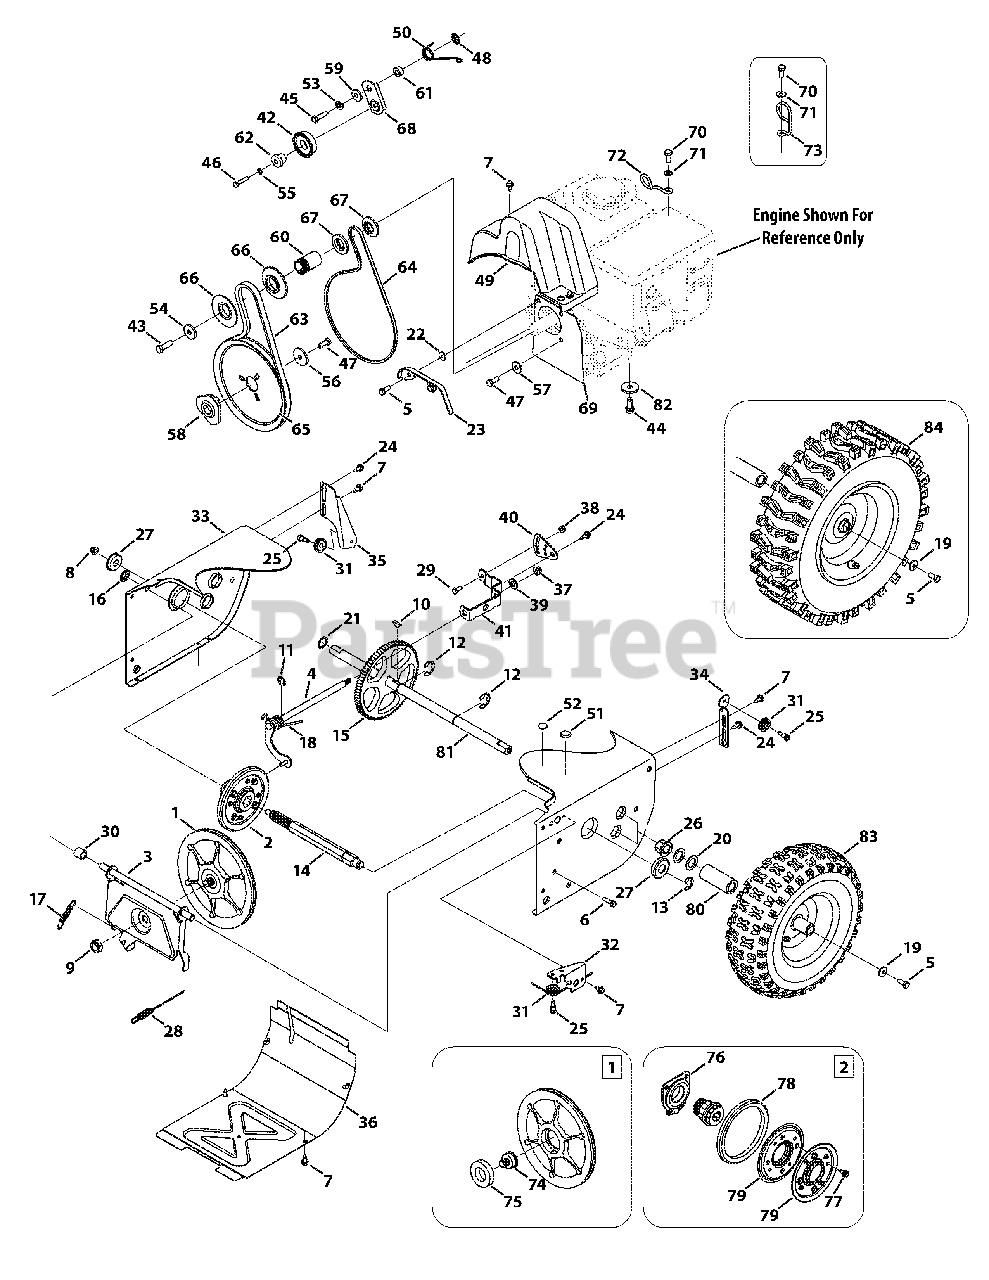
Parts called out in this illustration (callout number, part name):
1	Disc Assembly, Friction Wheel
2	Friction Wheel Assembly, 5.5 OD
3	Friction Wheel Support Bracket
4	Rod Shift Assembly
5	Hex Head Screw, 5/16-24 x .750
6	Taptite Screw, 1/4-20 x 1.000
7	Taptite Screw, 1/4-20 x .625
8	Flange Lock Nut, 3/8-16
9	Flange Nut, 5/8-18
10	Hi-pro Key, 3/16 x 3/4 Dia.
12	Retaining E-ring, .875 Dia.
13	E-ring, .750 Dia.
14	Hex Shaft, 7-Tooth
15	Gear, 80-Tooth
16	Speed Nut, .500
17	Extension Spring
18	Torsion Spring, .750 x .968
19	Bell Washer, .340 x .872 x .060
20	Flat Washer, .793 x 1.24 x .060
21	Flat Washer, .75 x 1.00 x .060
22	Washer, Flat, .385 x .62 x .063
23	Belt Cover
24	Shoulder Screw, .368 x .113, 1/4-20
25	Shoulder Screw, 1/4-28, .340 x .355
26	Hex Flange Bearing
27	Ball Bearing, 17 x 40 x 12
28	Wheel Clutch Cable, 44.95"
29	Hex Head Screw, 1/4-20 x .620
30	Spacer, .508 ID x .75 OD x .68
31	Cable Roller
32	Auger Cable Front Guide Bracket
33	Frame - Red
34	Auger Cable Guide Bracket
35	Drive Cable Guide Bracket
36	Frame Cover - Red
37	Flange Lock Nut, 5/16-18
38	Flange Lock Nut, 1/4-20
39	Washer, Flat, .469 x .875 x .105
40	Speed Selector Pivot Bracket
41	Speed Selector Shift Bracket
42	Idler Pulley Assembly
43	Hex Screw, 3/8-24 x 1.25
44	Sems Screw, 3/8-16 x 1.00
45	Hex Screw, 5/16-24 x 1.25
46	Hex Screw, 1/4-20 x 1.25
47	Hex Screw, 5/16-24 x .875
48	Push-on Nut, .25 Dia.
49	Belt Cover - 28" Models
49	Belt Cover - 26" Models
49	Belt Cover - 24" Models
50	Torsion Spring, .850 ID x .333
51	Plug, 3/8 ID
52	Plug, 1/2 ID
53	Lock Washer, 5/16
54	Flat Washer, .406 x 1.25 x .157
55	Washer, Lock, 1/4
56	Flat Washer, .34 x 1.50 x .150
57	Shoulder Space
58	Adapter Pulley, .75 Dia.
59	Shoulder Spacer, .3175 x .5 x .0975
60	Spacer, .875 ID x 1.185 OD
61	Spacer, .340 x .750 x .330
62	Shoulder Space, .260 x .785 x .538
63	Auger Drive Belt - 28" Models
63	Auger Drive Belt - 24" & 26" Models
64	Wheel Drive Belt - 28" Models
64	Wheel Drive Belt - 24" & 26" Models
65	Auger Drive Pulley, 8.1 x .5
66	Pulley Half, 2.600 OD
67	Pulley Half, 3/8 x 1.716 OD
68	Wheel Drive Idler Bracket
69	Cover Plate - 28" Models
69	Cover Plate - 26" MOdels
70	Hex Head Screw, 1.25 x 20
71	Washer, Flat, .330 x .630 x .0635
72	Cable Guide
73	Cable Guide
74	Disc Bearing Friction Pin
75	Ball Bearing, 30 x 55 x 13
76	Bearing Assembly
77	Screw, 1/4-14 x .625
78	Friction Wheel Rubber
79	Friction Wheel Plate
80	Spacer, 1.25 x .75 x 3.0
81	Axle, .75 x 22
82	Washer, Flat, .38 x 1.38 x .125
83	Not used in this application
84	X-Trac Wheel, 13 x 4 x 6, LH - 24" Models
84	X-Trac Wheel, 13 x 4 x 6, RH - 24" Models
84	X-Trac Wheel, 15 x 5 x 6, LH - 26" Models
84	X-Trac Wheel, 15 x 5 x 6, RH - 26" Models
84	X-Trac Wheel, 16 x 4.8 x 8, LH - 28" Models
84	X-Trac Wheel, 16 x 4.8 x 8, RH - 28" Models
